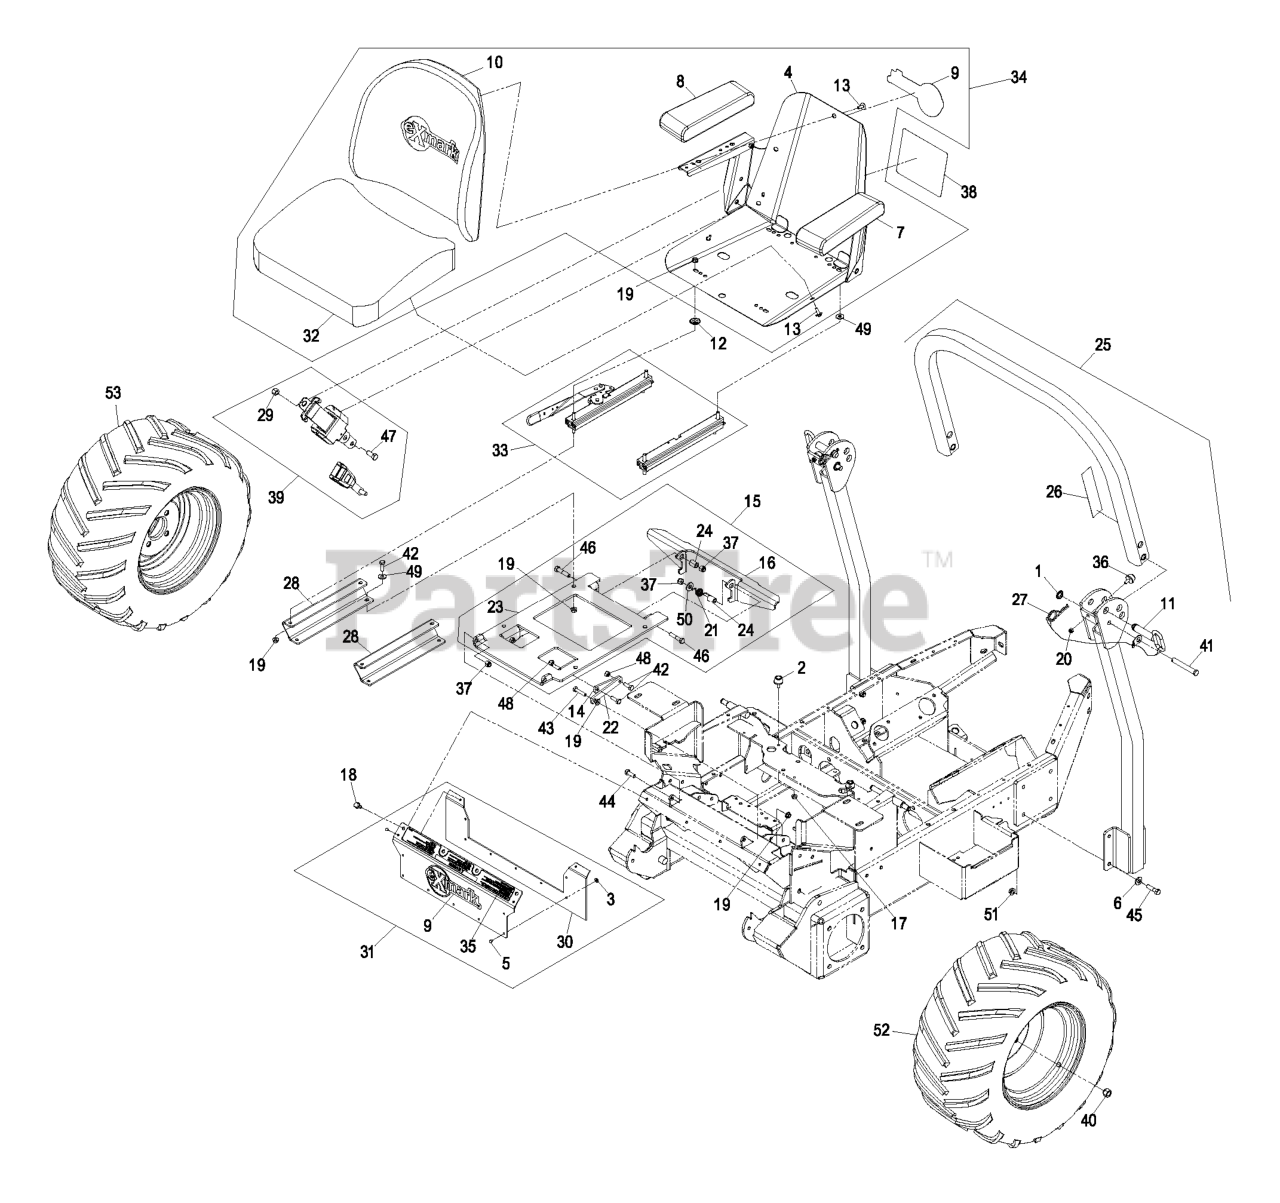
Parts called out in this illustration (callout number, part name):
1	NUT-PUSH
3	WASHER-FLAT
4	FRAME-SEAT
5	RIVET-POP
6	WASHER-BELLEVILLE
7	CUSHION,ARMREST LH
8	CUSHION,ARMREST RH
9	DECAL,EXMARK LOGO
10	CUSHION,SEAT BACK
11	PIN-FOLD, ROPS
12	SPACER-TRACK
13	BOLT-SEAT
14	LINK-STOP, SEAT
15	ASM, SEAT FRAME FMZ
18	SCREW-HWH, THREAD CUT
20	NUT-LOCK, NI
22	LINK,FMZ LWR SEAT STOP (P
24	BUSHING-LEVER, LIFT
25	KIT,ROPS FMZ
26	DECAL-WARNING, FOLDING RO
27	HAIRPIN
28	Spacer, Seat Mount
29	NUT-LOCK
30	Skirt, Rubber
31	ASM,FRONT CONSOLE W/ DECA
35	DECAL,TOP CONSOLE
36	BUMPER-RUBBER
37	NUT-LOCK, NI
38	Decal, Service Aid
40	NUT-LUG
41	PIN-CLEVIS
42	SCREW-HH
43	SCREW-HH
44	SCREW-HH
45	SCREW-HH
46	SCREW-HH
47	SCREW-HH
48	NUT-LOCK, NI
49	WASHER-FLAT
50	WASHER-FLAT
51	NUT-HHF, WHIZ
52	Asm, Wheel & Tire (Lh)
53	Asm, Wheel & Tire (Rh)
